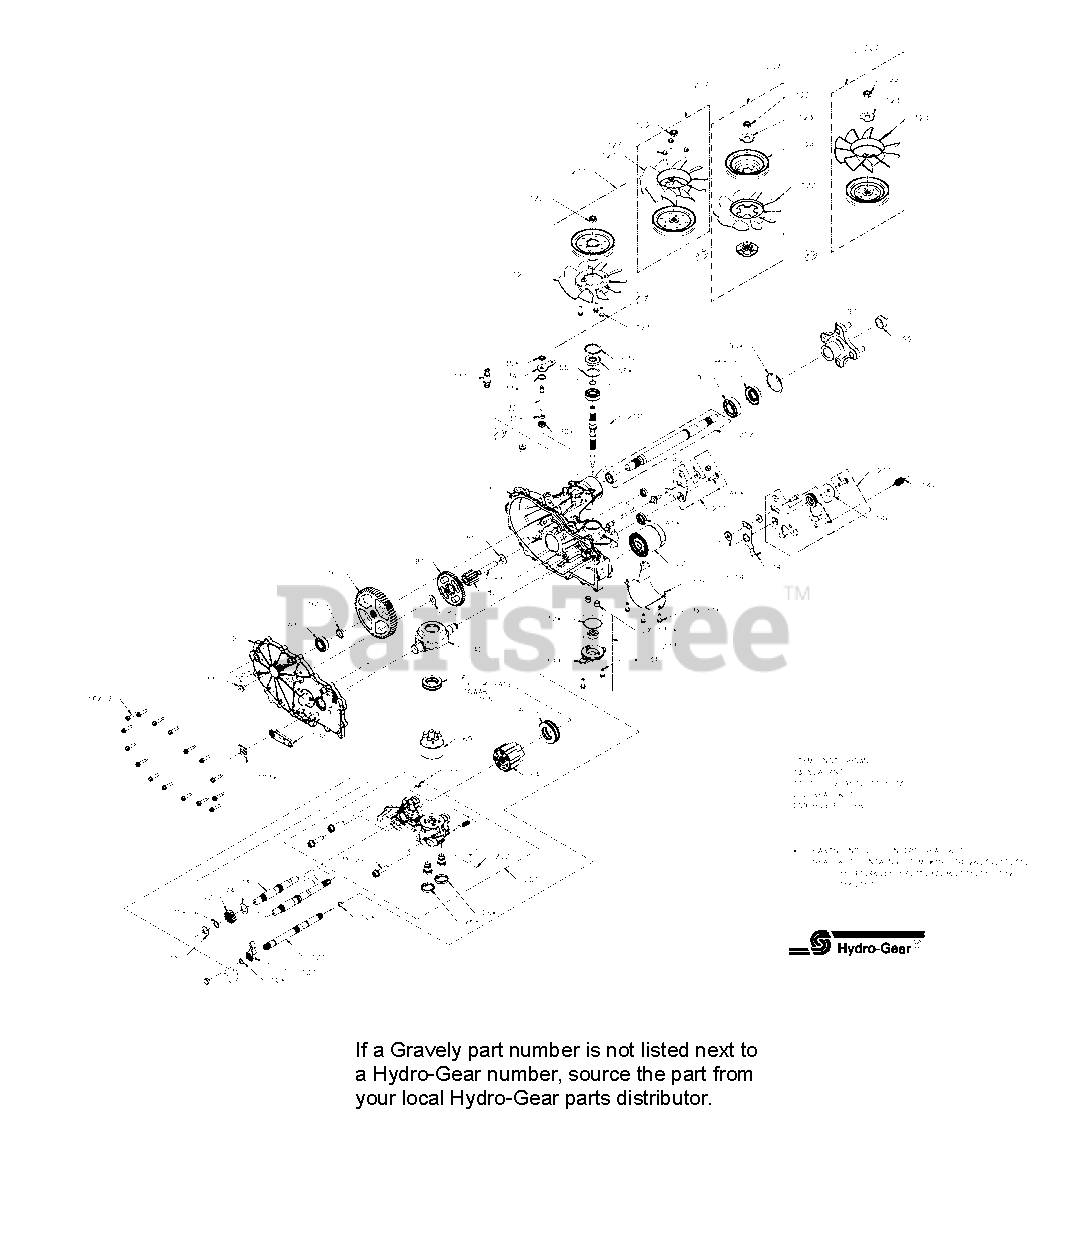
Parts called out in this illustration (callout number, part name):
1	KIT, HOUSING, MAIN, LH, CHRG, CNTL
2	KIT, COVER, SIDE, LH
7	HFHCS 1/4-20 x 1.125"
10	O-RING - 111 .103 x .424
11	PLUG 9/16-18 (METAL)
13	SEALANT
14	OIL, 20W50
22	PLATE, BYPASS
23	FILTER, OIL
26	SEAL, PLUG 1.250 x .250
27	HFHCS 3/8-16 x 1.5 (PATCH)
30	SEAL, LIP .375 x .75 x .25
31	RING, RET .375 EXTRNL
32	ROD, BYPASS
33	RING, RET .750 INTRNL
34	ARM, BYPASS
35	RING, RTNG .375 EXT
40	TRUNNION, SWASHPLATE
41	SEAL, LIP 12 x 32 x 7
45	WASHER .34 x .88 x .06
46	TWHCS 5/16-24 x 1.00 (PATCH)
55	WASHER 1.23 x 1.56 x .04
56	SEAL, LIP 17 x 40 x 7
57	RING, RETAINING
60	BEARING, THRUST
64	ASS'Y, CYLINDER BLOCK, 16cc
65	BRG, THRUST BALL 30 x 52 x 13
69	ASS'Y, BLOCK 7 PISTON
70	WASHER .63 x 1.0 x .05
71	RING, RETAINING_.625
72	GEAR, 16T
73	SHAFT, MOTOR
74	WASHER .72 x 1.16 x .04
80	WASHER .5 x 1.0 x .03
81	GEAR, 43T
82	GEAR, 11T
83	JACK SHAFT (PIN)
90	RING, RET 2.06 INT
91	GEAR, 54T
92	SPACER, .75 x 1.32 x .257
93	BEARING, BALL, .75 x 40 x 12
95	BRG, BALL 1.0 x 52 x 15 OPEN 6205M
96	SEAL, LIP 25 x 52 x 10 TC (GRAY)
97	KIT, HUB, 4 BOLT
99	NUT, HEX LOCK 3/4-16
100	PAWL, BRAKE
101	SHAFT, BRAKE
102	HANDLE, ACTUATING
103	CLIP, RETAINING
105	HFHCS 1/4-20 x .75
106	GUARD, FILTER, LH
111	FITTING, STR 9/16-18 SAE .5 BARB
120	FAN 7", 10 BLADE
122	NUT, HEX JAM 1/2-20 W/PATCH
123	HFHCS 1/4-20 x .875
130	TUBE, CONNECTING
131	GEROTOR ASSEMBLY (1.9 cc/rev)
132	O-RING, -137, 0.103 x 2.050
133	COVER, CHARGE PUMP
134	HFHCS 1/4-20 x .75
140	SPACER .320 x 1.005 x .179
141	ARM, NEUTRAL LEFT
142	SHCS 5/16-24 x 1 PATCH
146	WASHER, .343 x 1.500 x .062
147	SPRING, EXTNSN RTN-34-LBS
200	KIT, SEAL
201	KIT, CENTER SECTION, LH, CHRG
202	KIT, CHARGE RELIEF
203	KIT, CHARGE PUMP
207	KIT, FAN & PULLEY
209	HUB PULLER, 4 BOLT
210	KIT, INPUT SHAFT
211	KIT, RTN, CCW
212	KIT, SHAFT, AXLE
